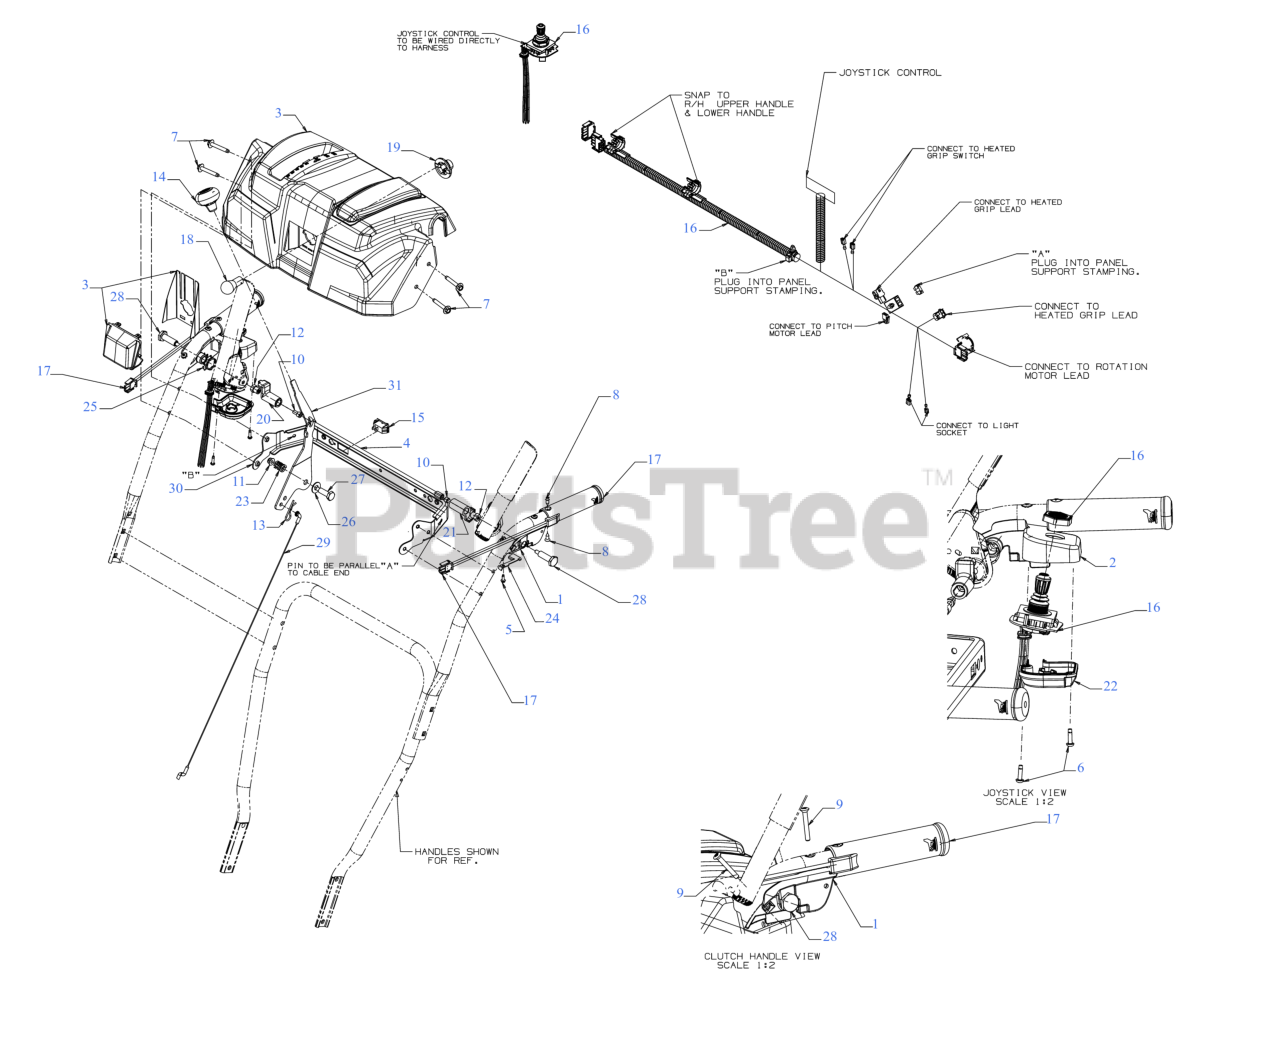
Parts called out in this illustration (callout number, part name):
1	CLUTCH LOCK HANDLE ASSEMBLY (LH)
2	CLUTCH HANDLE ASSEMBLY (RH)
3	HANDLE PANEL ASSEMBLY
5	SCREW #8-16 x .50
6	SCREW .159 x .610
7	SCREW 1/4-20 x 1.625
8	SCREW-AB #12-24 x .625
9	SCREW #10-24 x 1.375
10	SCREW 1/4-20 x .50
11	FLANGE LOCK NUT
12	HEX NUT W/PATCH
13	INTERNAL COTTER PIN
14	SHIFT KNOB
15	HEATED GRIP SWITCH
16	4-WAY ELEC/HEAT GRIP HARNESS
17	HEATED GRIP
18	LAMP-12 VOLT
19	HEADLIGHT SOCKET (1/4 TURN)
21	CLUTCH LOCK CAM
22	JOYSTICK HOUSING COVER
23	COMPRESSION SPRING
24	CLUTCH SPRING
25	TORSION SPRING
26	FLAT WASHER .40X.88X.060
27	SHOULDER SCREW
28	SHOULDER SCREW .437 x 1.345 1/4-20
29	SPEED SELECTOR CABLE (PLASTIC)
30	HANDLE SUPPORT BRACKET (POWDER BLACK)
